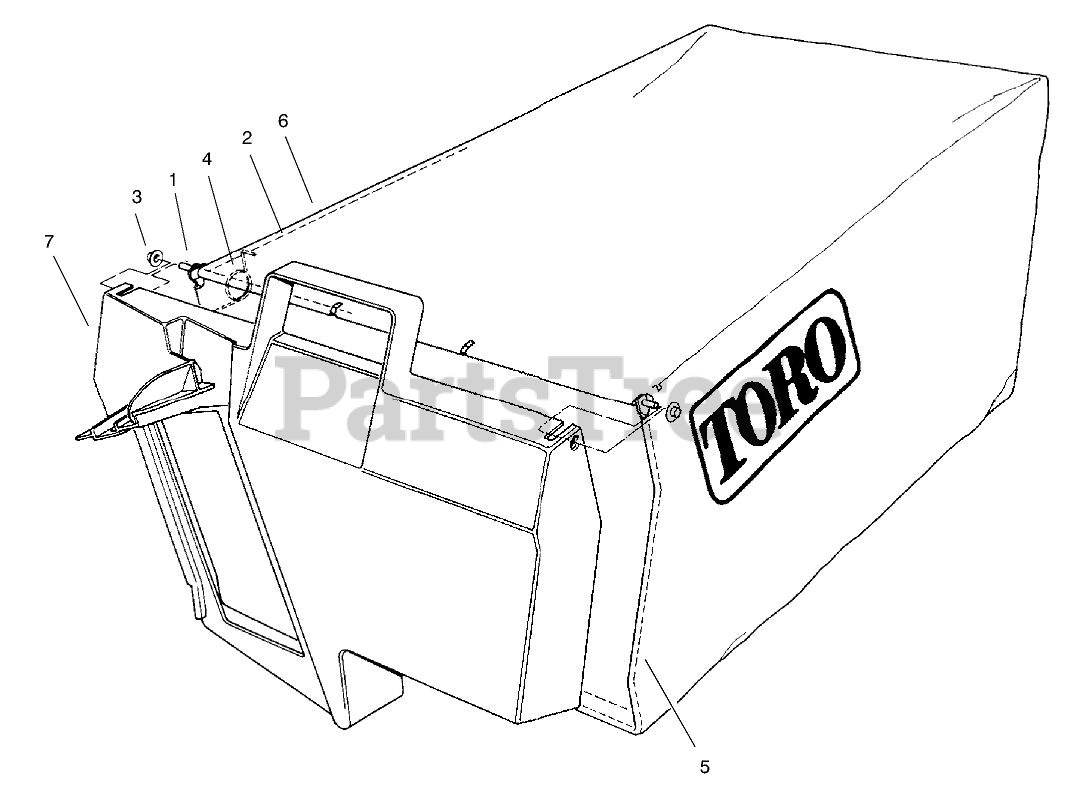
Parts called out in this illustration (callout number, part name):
1	HINGE-DOOR, BAG
2	FRAME-BAG, UPPER
3	NUT-PUSH
4	SPRING
5	FRAME-BAG
6	Bag-Grass
7	DOOR-BAG, GRASS
